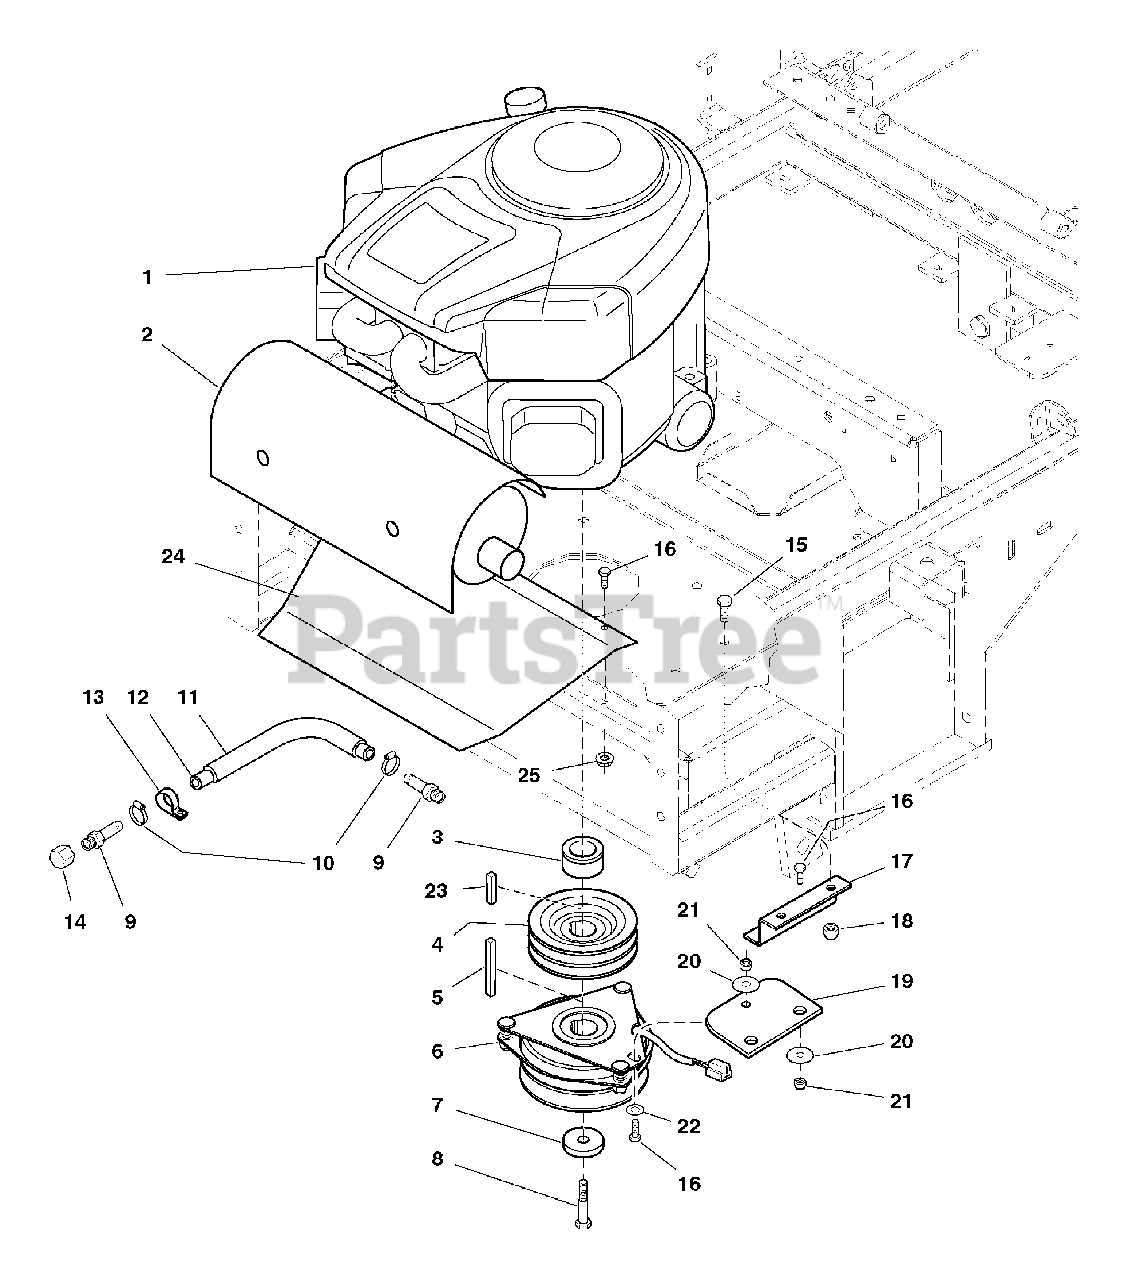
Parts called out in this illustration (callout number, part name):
1	ENGINE, 25HP Briggs & Stratton
3	CRANKSHAFT SPACER
4	CRANKSHAFT PULLEY
5	KEY, 1/4 Sq. x 2-1/2
6	ELECTRIC CLUTCH
7	RETAINER, Clutch
8	CRANKSHAFT BOLT, 7/16 x 1-3/4
9	FITTING, 3/8NPT - 1/2 Str.
11	WIRE LOOM, 12"
13	CLAMP, Vinyl
14	CAP, 3/8NPT
15	CAPSCREW, Hex Hd, 3/8-16 x 1
16	CAPSCREW, Hex Hd, 5/16-18 x 3/4
17	ANCHOR, CLUTCH - BLK
18	NUT, Hex, Nylon Lock, 3/8-16
19	PAD, Clutch Anchor
20	WASHER, Fender, 5/16
21	NUT, Hex, Nylon Lock, 5/16-18
22	WASHER, 5/16
23	KEY, 1/4 Sq. x 1
24	HEAT SHIELD
25	NUT, Hex, Serrated Flange, 5/16-18
